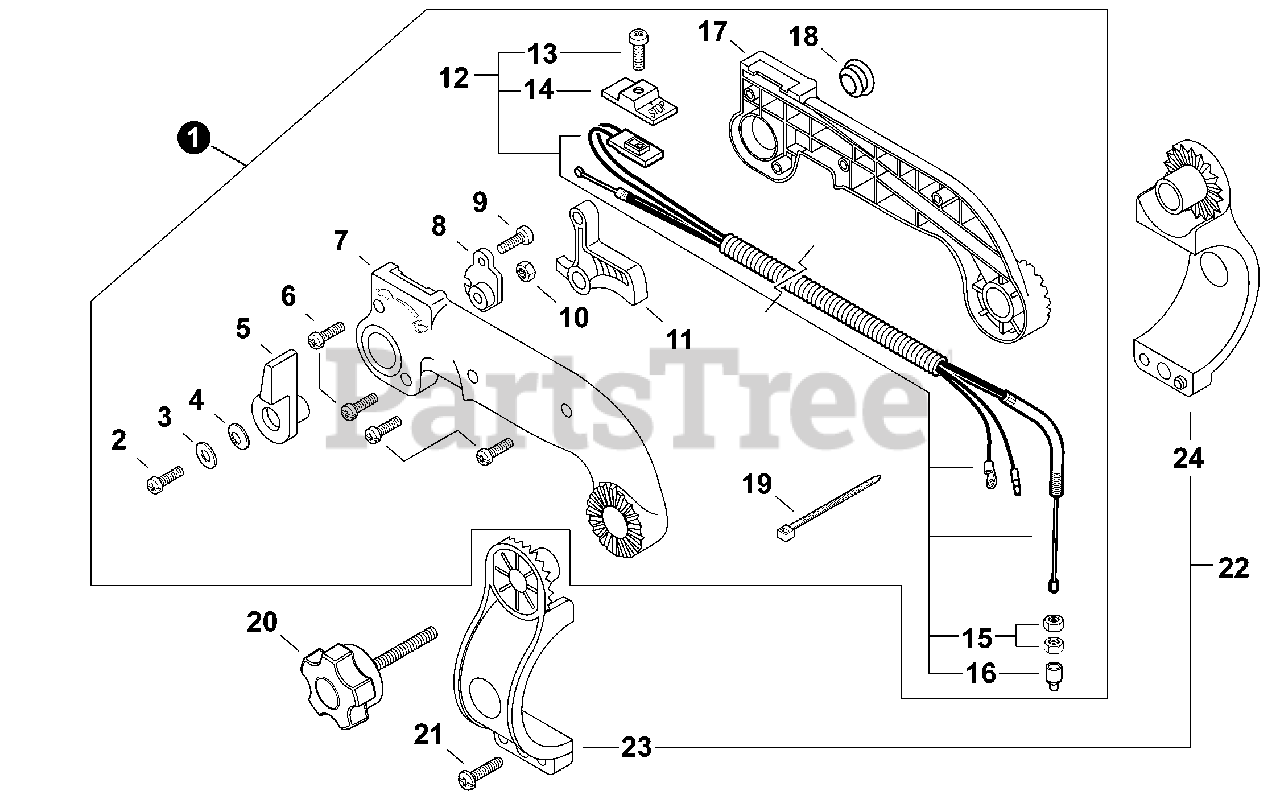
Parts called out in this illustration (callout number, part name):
1	THROTTLE CONTROL KIT - TUBE MOUNT
2	SCREW 6×20
3	WASHER, SPRING 6
4	WASHER 6.5×13×1
5	CONTROL, THROTTLE
6	SCREW 4×22
7	CONTROL HANDLE - LEFT
8	BRACKET, THROTTLE
9	SCREW 4×10
10	NUT, HEX M6
11	TRIGGER, THROTTLE
12	CABLE ASSY, CONTROL
13	SCREW 3×10
14	KNOB, SWITCH - RED
15	NUT 6 MM
16	CAP, DUST
17	CONTROL HANDLE - RIGHT
19	STRAP, TIE
20	KNOB, SCREW
21	SCREW, TAPPING 5×20
22	BRACKET KIT, HANDLE
23	BRACKET, HANDLE - LEFT
24	BRACKET, HANDLE - RIGHT
